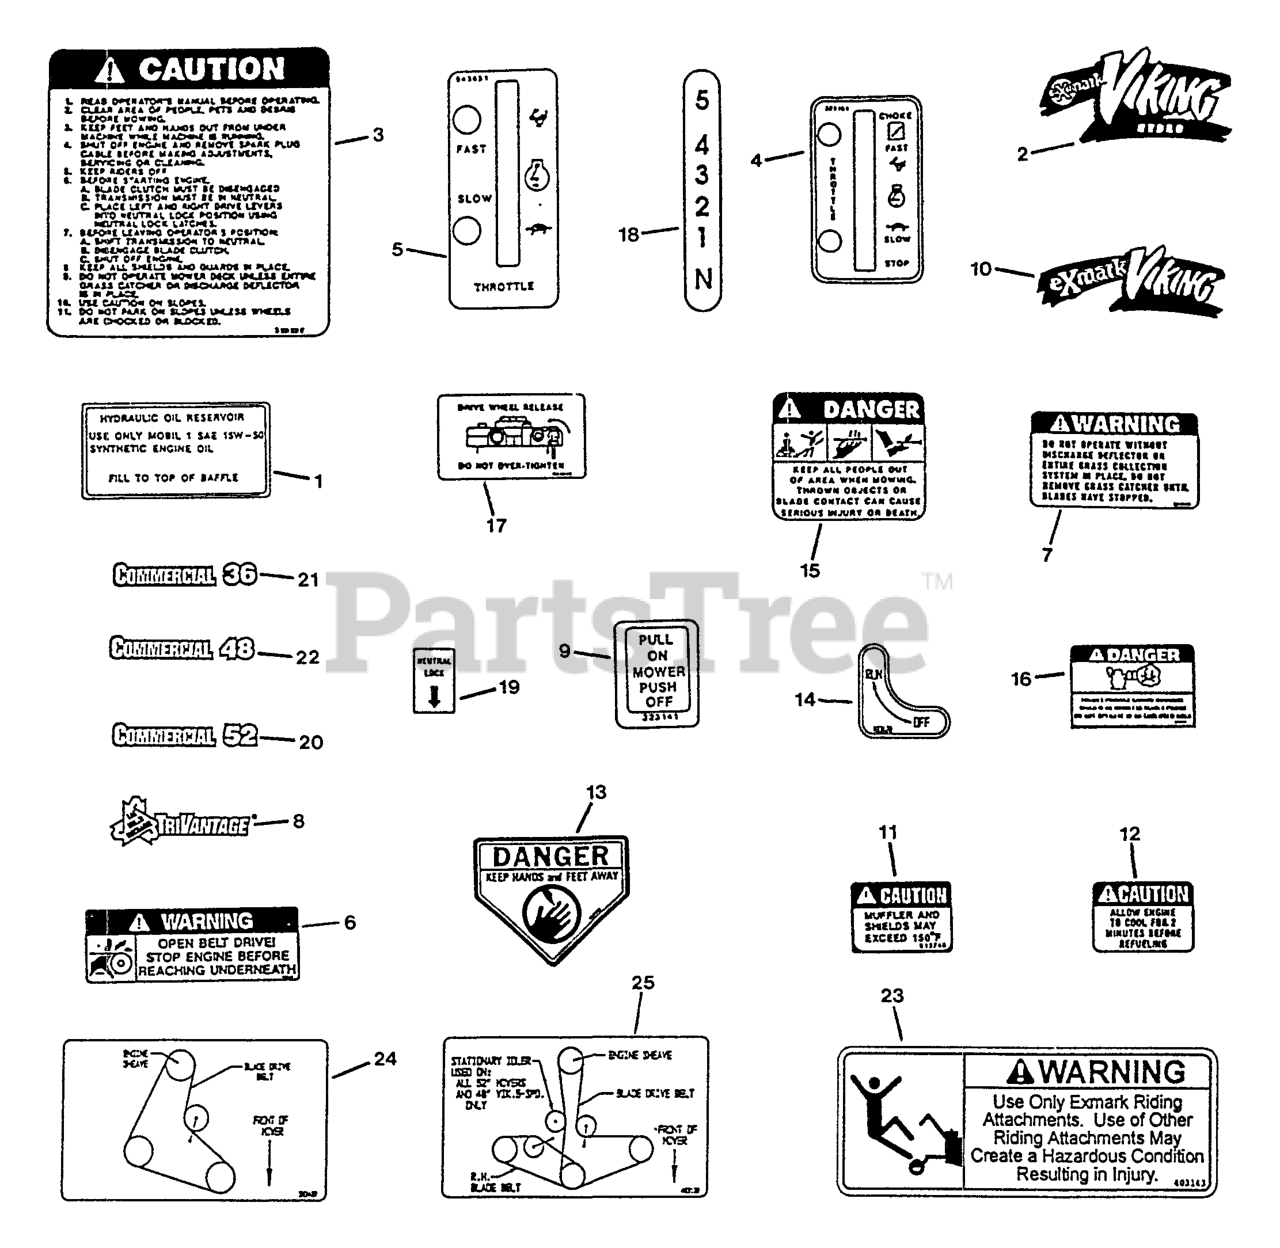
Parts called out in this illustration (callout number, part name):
1	DECAL,HYD TANK
3	DECAL,INSTRUCTIONAL
6	DECAL,BELT DRIVE
7	DECAL-WARNING, DISCHARGE
13	DECAL-DANGER
15	DECAL-DANGER
17	DECAL,DRIVE RELEASE
18	DECAL - SHIFTER
19	DECAL,NEUTRAL LOCK
20	DECAL,COMMERCIAL 52
21	DECAL,COMMERCIAL 36
22	DECAL,COMMERCIAL 48
23	DECAL,SULKY WARNING
24	DECAL,BELT ROUTING 32/36
